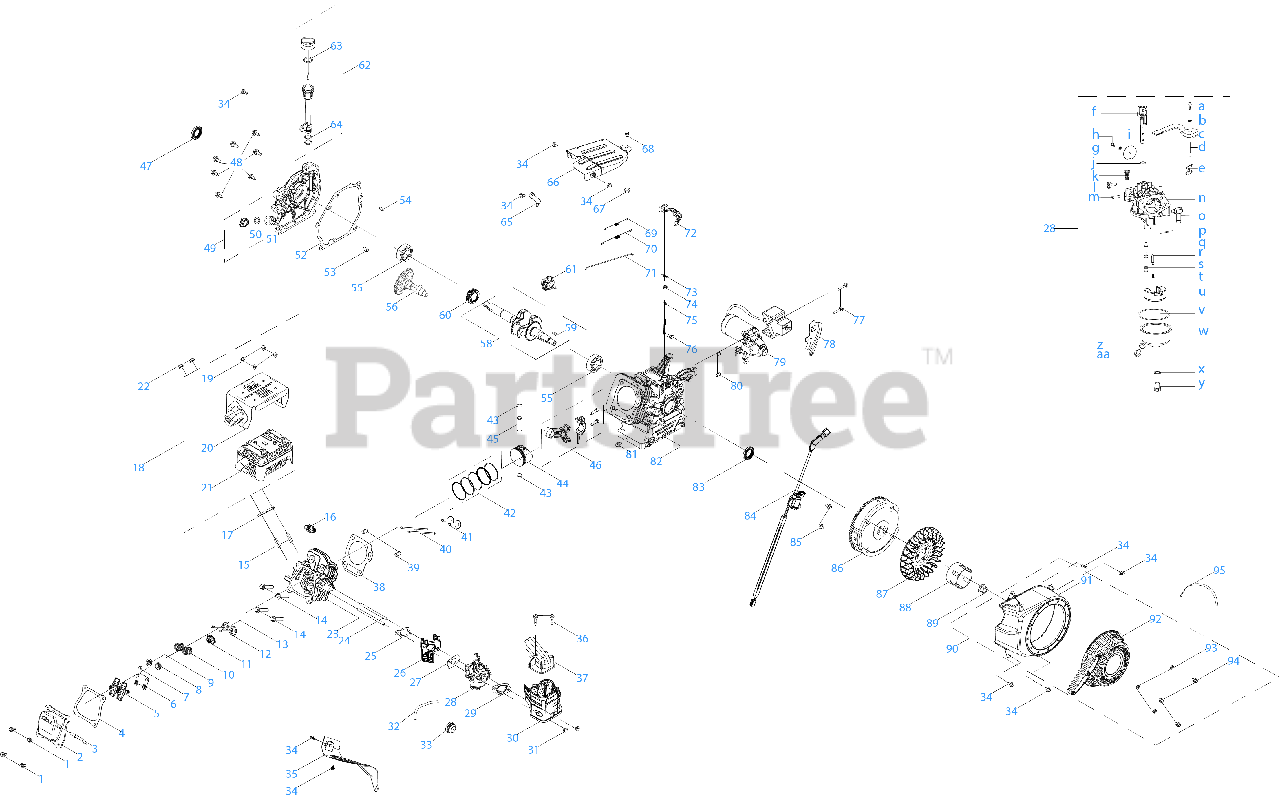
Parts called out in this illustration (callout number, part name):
1	BOLT M6 x 16
2	VALVE COVER
3	BREATHER HOSE
4	VALVE COVER GASKET
5	ROCKER ARM ASSEMBLY
6	ROCKER ARM BASE
7	EXHAUST VALVE ADJUSTER
8	INTAKE VALVE SPRING RETAINER
9	EXHAUST VALVE SPRING RETAINER
10	VALVE SPRING
11	INTAKE VALVE SEAL
12	INTAKE VALVE
13	EXHAUST VALVE
14	BOLT M8-1.25 x 55 GR10.9
15	STUD M8 x 36
16	SPARK PLUG
17	MUFFLER GASKET
18	MUFFLER ASSEMBLY
19	BOLT M5-.8 x 8 CL10.9
20	OUTER MUFFLER SHIELD
21	MUFFLER ASSEMBLY
23	CYLINDER HEAD
24	STUD M6-1 x 110 GR8.8
25	CARBURETOR INSULATOR GASKET
26	CARBURETOR INSULATOR
27	CARBURETOR GASKET
28	CARBURETOR ASSEMBLY HY-170-JA
29	CARBURETOR GASKET PLATE
30	HEATER BOX HOUSING
32	FUEL HOSE 3.2X6.5X530
34	BOLT M6-1 x 12 GR8.8
35	AIR SHIELD
36	BOLT M4.2 x 16
37	INTAKE HEATER BOX
38	CYLINDER HEAD GASKET
39	DOWEL PIN
40	PUSH ROD
41	TAPPET
42	PISTON RING SET
43	PISTON PIN SNAP RING
44	PISTON
45	PISTON PIN
46	CONNECTING ROD ASSEMBLY
47	OIL SEAL
48	BOLT M8-1.25 x 32 GR5.8
49	OIL PLUG
50	O-RING 15.8 x 2.5
51	CRANKCASE COVER
52	CRANKCASE COVER GASKET
53	DOWEL PIN
54	DOWEL PIN
55	BEARING
56	CAMSHAFT
58	CRANKSHAFT
59	FLYWHEEL KEY
60	DRIVE TIMING GEAR
61	GOVERNOR GEAR/SHAFT ASSEMBLY
62	DIPSTICK ASSEMBLY
63	DIPSTICK O-RING
64	OIL FILL TUBE O-RING
65	GOVERNOR SPRING BRACKET
66	GOVERNOR SHIELD
67	HEX NUT
68	BOLT-M6-1 x 28 GR8.8
69	GOVERNOR SPRING
70	THROTTLE RETURN SPRING
71	GOVERNOR ROD
72	GOVERNOR LEVER
73	COTTER PIN
74	GOVERNOR SEAL
75	O-RING
76	GOVERNOR SHAFT
77	BOLT M6-1 x 32 GR8.8
78	LOWER HOUSING
79	ELECTRIC STARTER
80	DOWEL PIN
81	OIL PLUG 1/8 NPT
82	CRANKCASE
83	OIL SEAL
84	IGNITION COIL ASSEMBLY
85	BOLT M6-1 x 25 GR8.8
86	FLYWHEEL
87	COOLING FAN
88	STARTER CUP
89	FLYWHEEL NUT
90	RECOIL HOUSING ASSEMBLY
91	BLOWER HOUSING
92	RECOIL STARTER HOUSING
93	RECOIL FLAT WASHER
94	BOLT M6 x 10
95	CABLE TIE - 3 x 150
